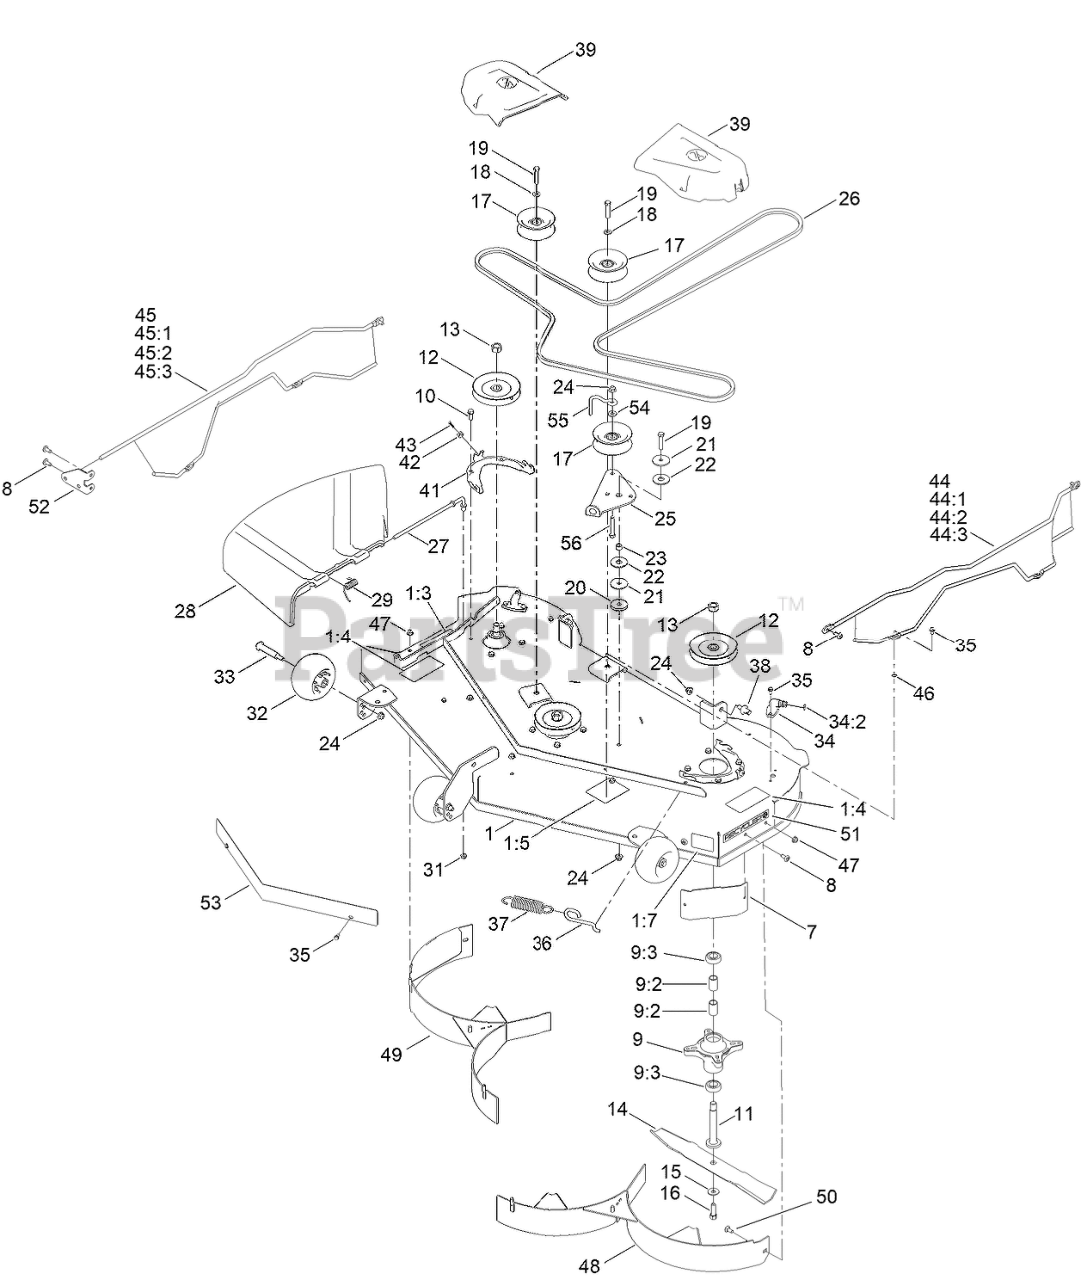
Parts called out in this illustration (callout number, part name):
1	50 INCH DECK AND DECAL ASM
1:3	DECAL-DANGER
1:4	DECAL-DANGER, DECK
1:5	DECAL-ROUTING, BELT
1:7	DECAL-SCALP, ANTI
7	BAFFLE-CORNER
9	SPINDLE ASM
9:2	SPACER
9:3	BEARING-BALL
10	SCREW-TAPTITE
11	SHAFT-SPINDLE
12	PULLEY
13	Nut-Hex
14	BLADE-MULCH, 17.50 INCH
15	WASHER-BELLEVILLE
16	SCREW-HH
17	PULLEY-IDLER, FLAT
18	WASHER-FLAT
19	SCREW-HH
20	WASHER-PLAIN
21	Washer
22	WASHER-FRICTION, COMPOSITE
23	SPACER
24	NUT-HF, NI
25	ARM-IDLER
26	V-BELT
27	ROD-PIVOT
28	DEFLECTOR-DISCHARGE
29	SPRING-TORSION
31	NUT-HEX
32	ROLLER-SCALP, ANTI
33	BOLT-SHOULDER
34	FITTING-WASHOUT
34:2	O-RING
35	SCREW-HWH
36	HOOK-RETURN SPRING
37	SPRING-EXTENSION
38	PIN-DECK
39	COVER-BELT
41	BRACKET-COVER, BELT
42	SPACER-NOTCHED
43	SCREW-PPH
44	LEFT GUARD ASM
44:2	ROD-TOP, LEFT
44:3	ROD-SUPPORT, LOWER
45	RIGHT GUARD ASM
45:2	ROD-TOP, RIGHT
45:3	ROD-SUPPORT, LOWER
46	NUT-RETAINING
47	NUT-HF
48	50IN BAFFLE ASM
49	50IN BAFFLE ASM
50	BOLT-CARR
51	DECAL-RECYCLER
52	PLATE-MOUNT, GUARD
53	SHIELD-FRONT
54	SPACER-HUB, BLOWER
55	BELT GUIDE - IDLER
56	SCREW-HH
